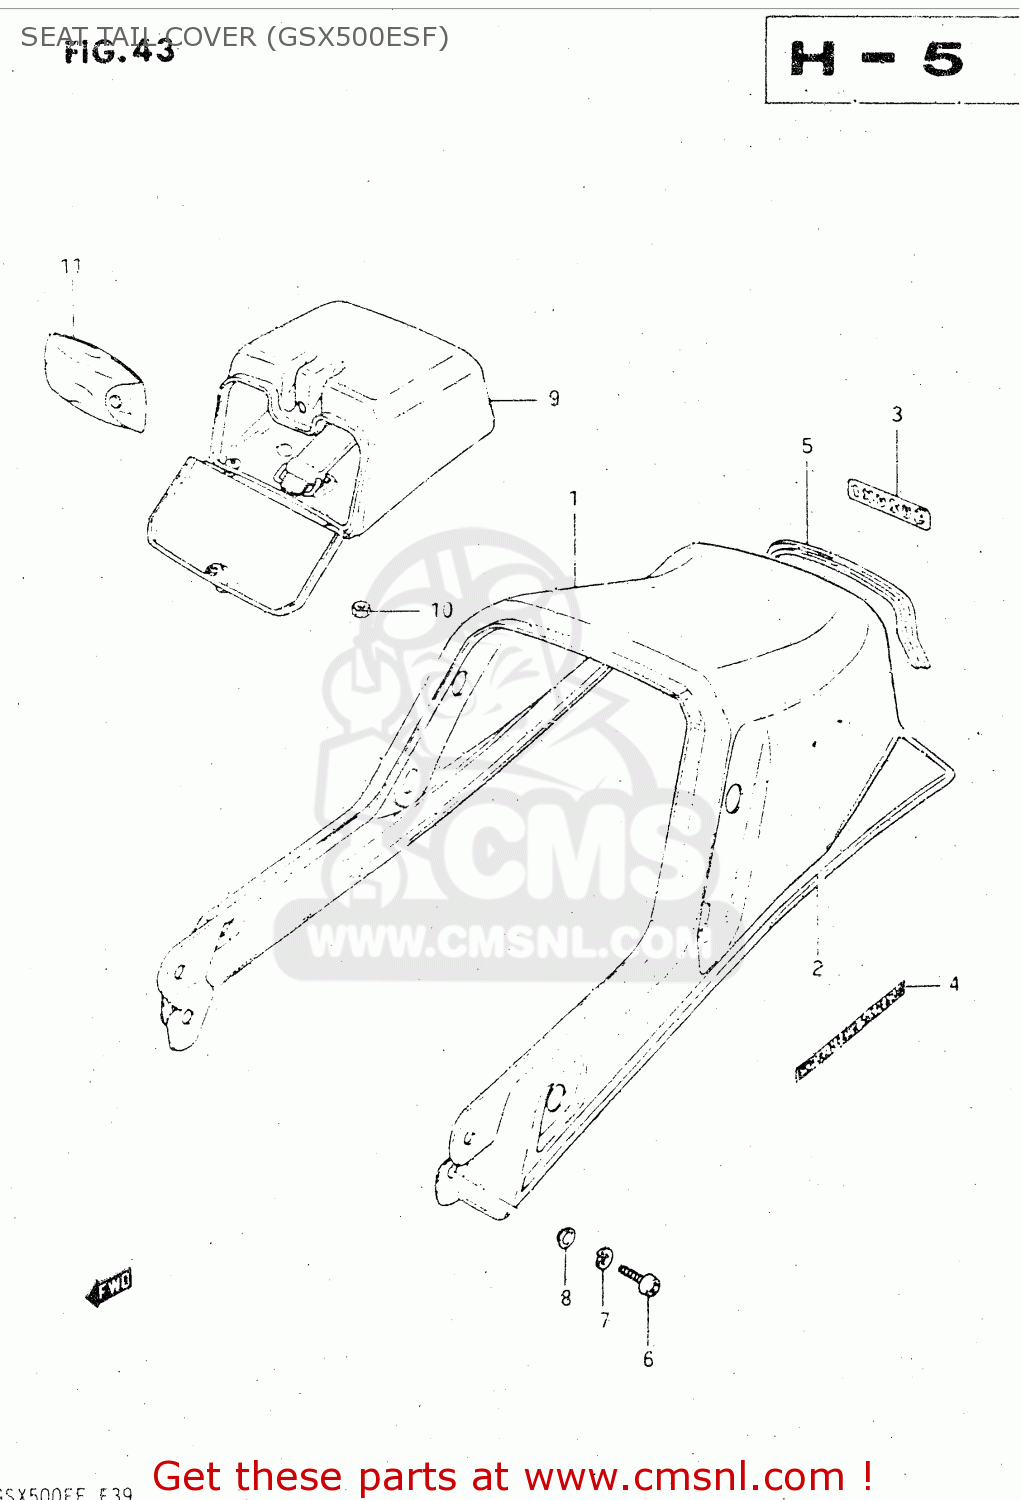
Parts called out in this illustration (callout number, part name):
1	COVER, SEAT TAIL
2	TAPE SET,SEAT TAIL COVER
3	EMBLEM(WHITE)
4	EMBLEM
5	BLIND,SEAT TAIL COVER
6	SCREW
7	LOCK WASHER
8	WASHER
9	BOX,SEAT TAIL
10	NUT
11	TOOL ASSY
